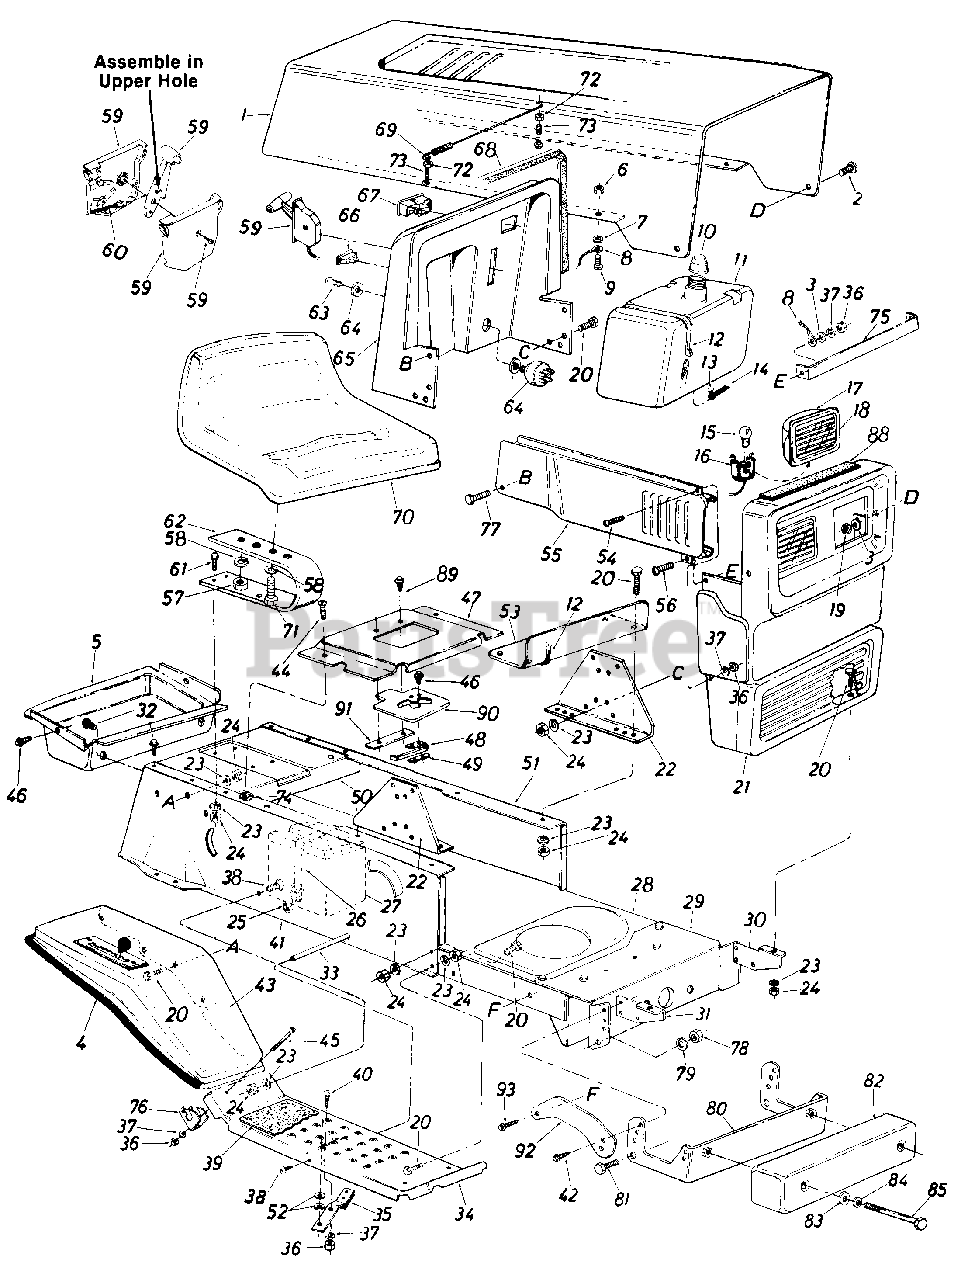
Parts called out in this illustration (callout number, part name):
1	Hood N
2	Truss Hex Scr. 1/4-20 x .62"
3	Fl-Wash. .296" I.D. x .62" O.D.
4	Trim Strip 27"
5	Tool Tray
6	Hex Sems Nut #10-24 Thd.
7	Fl-Wash. .203" I.D. x .41" O.D. x .040
8	Hood Stop
9	Truss Hd. Scr. #10-24 x 1/2" Lg.
10	Fuel Cap Gauge
11	Fuel Tank
12	Tie Strap
13	Hose Clamp
14	Fuel Line
15	Lamp
16	Socket
17	Headlight Housing
18	Lens
19	Hex L-Nut 1/4-20 Thd.
20	Hex Bolt 5/16-18 x .75" Lg.
21	Grille
22	Dash Support Bracket
23	L-Wash. 5/16" I.D.
24	Hex Nut 5/16-18 Thd.
25	Battery Strap Hook
26	Battery Hold Down Strap
27	12V Battery
28	Lower Frame
29	Front Pivot Brkt.
30	Grille Mount Brkt L.H.
33	Running Board Rod
34	Running Board
35	Blade Brake Ass'y.
36	Hex Nut 1/4-20 Thd.
37	L-Wash. 1/4" I.D.
38	Truss Mach. Scr. 5/16-18 x .75" Lg.
39	Foot Pad
40	Carriage Bolt 1/4-20 x .62"
41	R.H. Side Frame
42	Hex Wash. Hd. TT-Tap Scr. 5/16 x 1.0" Lg.
43	Rear Fender
45	Truss Hd. Scr. 1/4-20 x 1.75" Lg.
46	Truss Hd. Scr. #10-24 x .50"
47	Transmission Panel
48	Raverse Safety Switch
49	Insulator Nut Plate
50	Hitch Plate
51	L.H. Side Frame
52	Fl-Wash. .28" I.D. x .75"
53	Fuel Tank Support
54	Truss Hd. Scr. 1/4-20 x .75"
55	Side Cover R.H.
56	Truss Mach. Scr. 1/4-20 x .50" Lg.
57	Hex Nut 1/2-13 Thd.
58	L-Wash. 1/2" I.D.
59	Throttle Control Box Ass'y.
60	Throttle Control Wire
61	Hex Bolt 5/16-18 x 1.00"
62	Seat Spring 5.5" High
63	Ignition Key
64	Ignition Switch
65	Dash Panel
66	Light Switch
67	Ammeter
68	Trim Strip 27"
69	Hood Spring
70	Seat Ass'y.
71	Hex Bolt 1/2-13 x 1.0" Lg.
72	Hex Top L-Nut #10-24
73	Hex Bolt #10-24 x 1.0" Lg.
74	Speed Nut #10Z
75	Tie Strap Grille/Side Panel
76	Fender Clamp
77	Hex Wash. Hd. Tap Scr. 1/4 x.75" Lg.
78	Hex Nut 7/16-14 Thd.
79	L-Wash. 7/16" I.D.
80	Weight Brkt. Ass'y.
81	Hex Bolt 7/16-14 x 1.0" Lg.
82	Counter Weight 38#
83	Fl-Wash..39" I.D.
84	Bell-Wash. .39" I.D.
85	Hex Bolt 3/8-16 x 4.5" Lg.
88	Foam Strip 3/.8 x 1 x 14" Lg.
89	Truss Mach. Scr. 1/4-20 x .75" Lg.
90	GearSelection Plate
91	Clamping Plate
92	Weight Brkt. Tie Strap
93	Hex Self-Tap Scr. 3/8-16 x.88" Lg.
